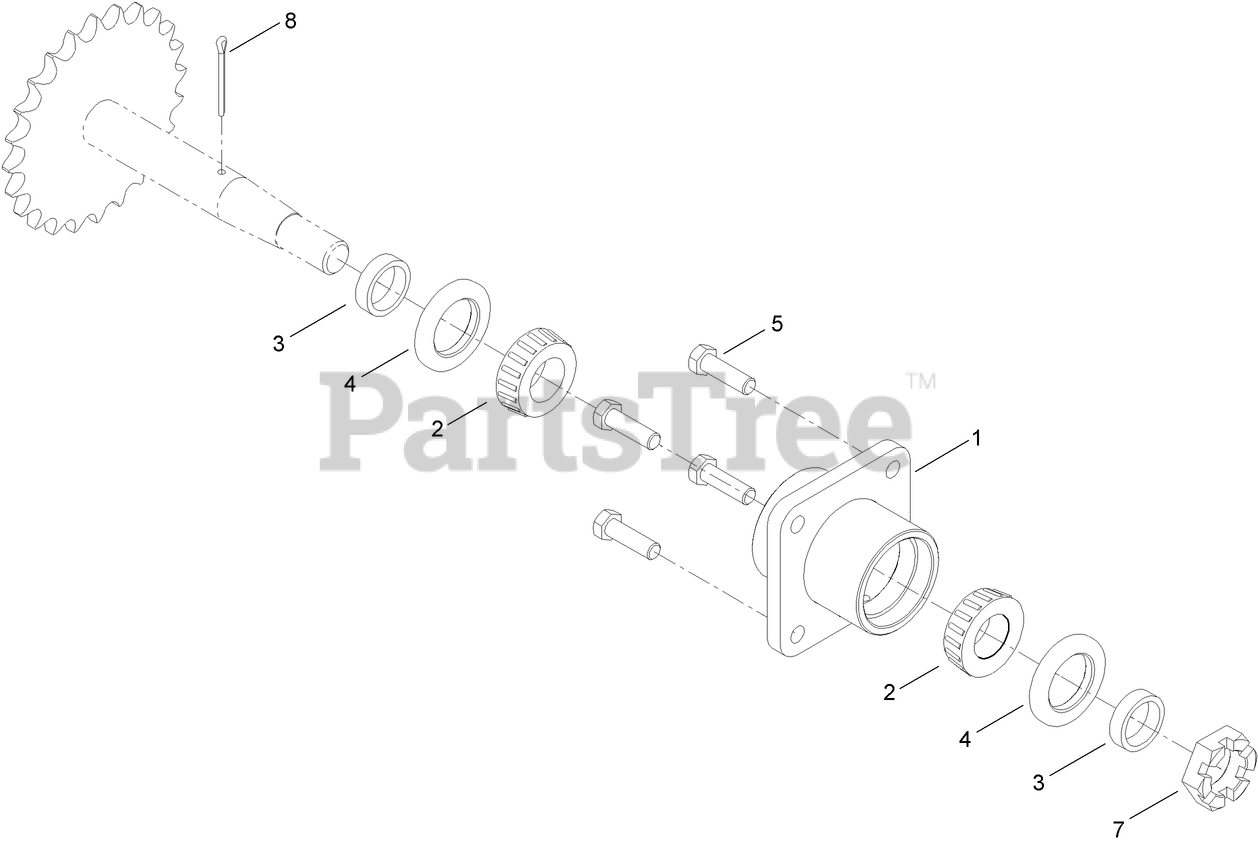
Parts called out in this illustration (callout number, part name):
1	MOUNT-BEARING, WHEEL
2	BEARING-ROLLER, TAPERED
3	SPACER
4	SEAL-GREASE
5	SCREW-HH
8	PIN-COTTER
